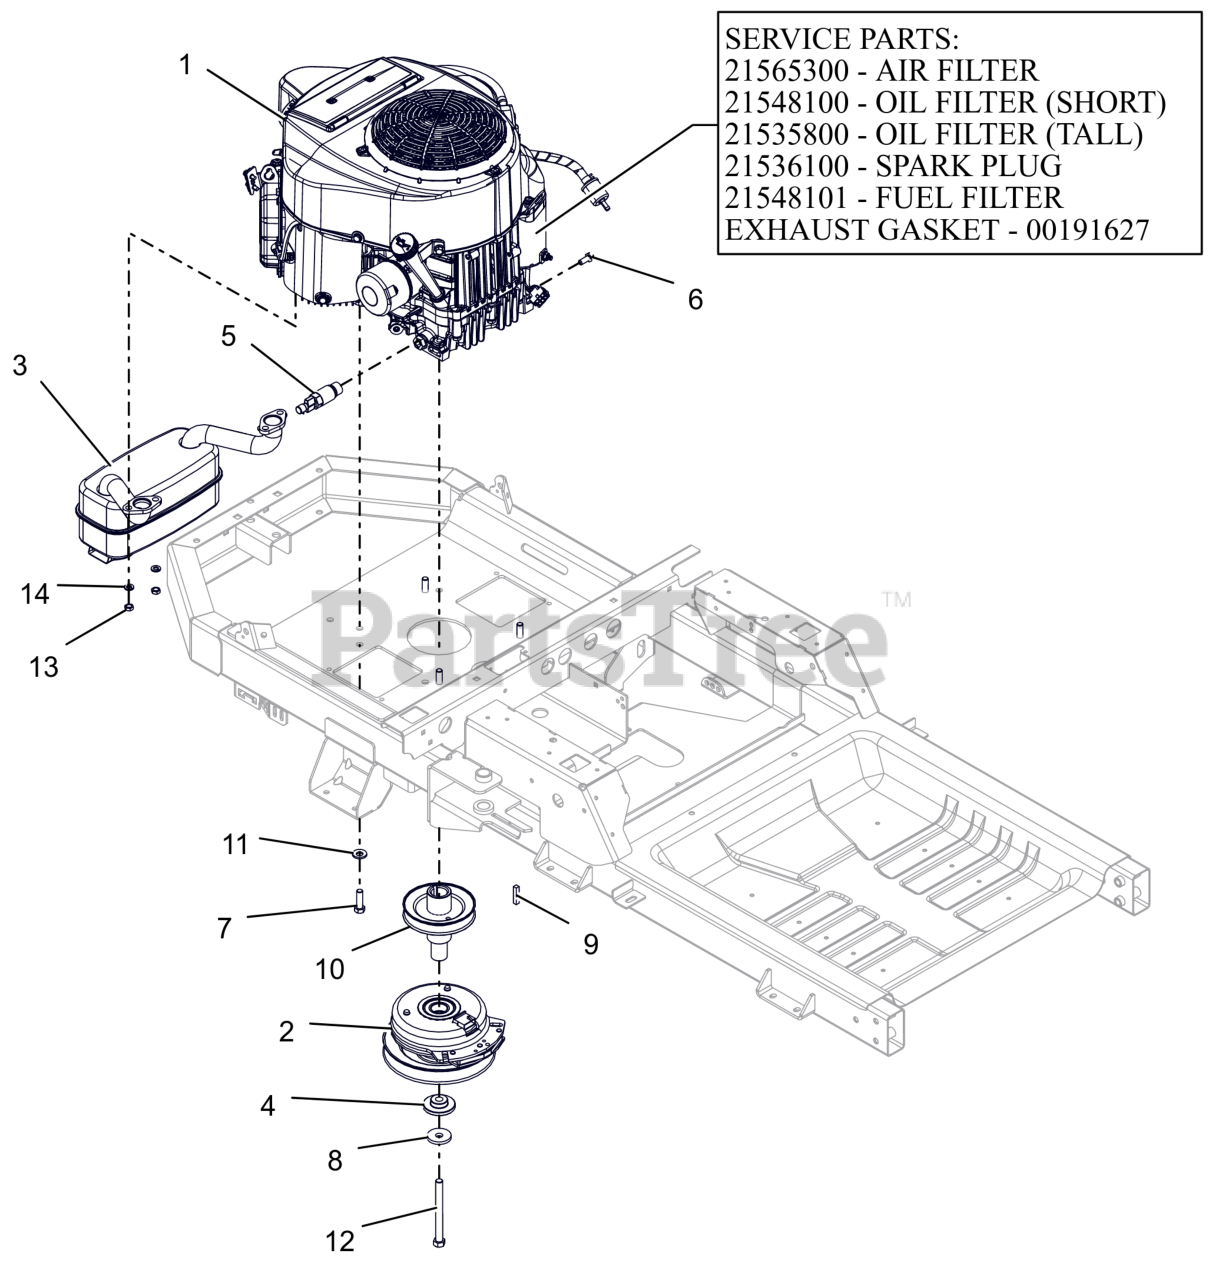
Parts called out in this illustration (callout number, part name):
1	ENGINE, KAWASAKI FR600
1	AIR FILTER, KAWASAKI FR
1	OIL FILTER, KAWASAKI FR
1	FILTER,OIL - KAW
1	PLUG, SPARK
1	FUEL FILTER-KAWASAKI FR
1	GASKET, MUFFLER S/O
2	CLUTCH,105FTLB MONOPOLE 6.83"
3	MUFFLER - KAWASAKI
4	BSHG-FLG .469X1.06X.574X2.0
5	DRAIN, OIL M20X2.5
6	BLT, HEX M8-1.25X20 G8.8 ZCC
7	BLT, HEX .38-16X1.25 G5 ZCC NT
8	WASHER, 7/16" SPRING DISK
9	KEY-SQ .25 X 1.25 X .25 SAE
10	WLDMT, DRIVE SHEAVE-X
11	WASHER, 3/8" SPRING DISC
12	BLT, HEX .44-20X4.50 G8 ZCC NT
13	NUT, LK-CTR-JAM M8-1.25 GR8.8 ZC120
14	WSHR,LK-REG .312X.078 ZCC
